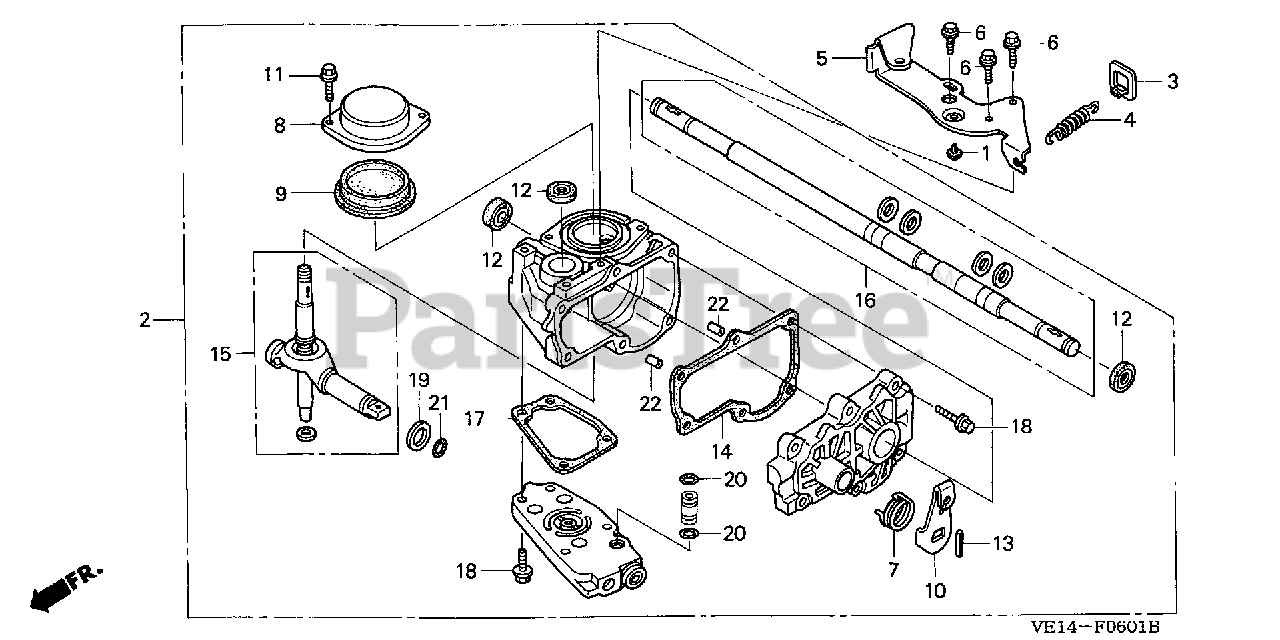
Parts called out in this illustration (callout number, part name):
1	RUBBER, TANK STOPPER
2	TRANSMISSION ASSY.
3	PLATE, TENSION SPRING
4	SPRING, WHEEL TENSION
5	HOLDER, WIRE
6	BOLT, FLANGE (6X16) (CT200)
7	SPRING, CONTROL ARM RETURN
8	CAP, OIL
9	GASKET, OIL CAP
10	ARM, CONTROL
11	BOLT, FLANGE (5X12)
12	OIL SEAL (13X22X5) (ARAI)
13	PIN, SPRING (4X25)
14	GASKET, TRANSMISSION CASE
15	SHAFT SET, PUMP (NA USE ALT:20011-VE5-711)
16	SHAFT SET, MOTOR (NA USE ALT:20011-VE5-711)
17	GASKET, DISTRIBUTOR
18	BOLT, FLANGE (6X28)
19	WASHER, THRUST (16MM)
20	O-RING (7.3X1.9) (NA USE ALT:20011-VE5-711)
21	O-RING (11.8X2.6) (NA USE ALT:20011-VE5-711)
22	PIN, DOWEL (8X10)
NI	KEY, WOODRUFF
